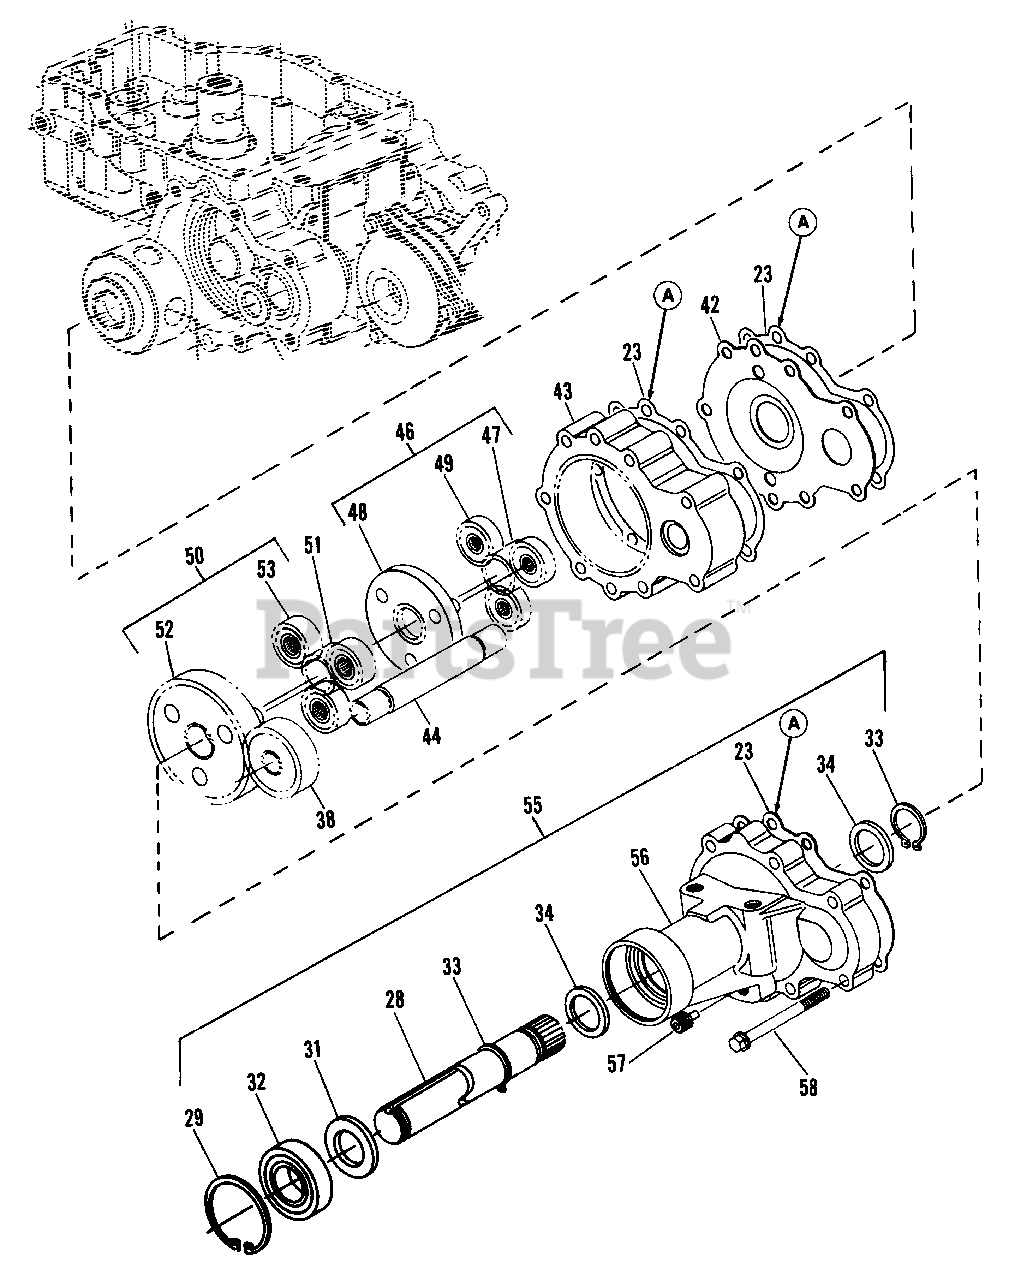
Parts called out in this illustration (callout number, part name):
23	GASKET, Axle Housing (See "A" Below)
28	SHAFT, Axle
29	RETAINING RING, Internal
31	LIP SEAL, Radial
32	BEARING, Ball
33	RING, Retainer
34	WASHER, Thrust
38	LOCK GEAR, Diff.
42	PLATE, Wear
43	RING GEAR, 54 Tooth
44	BRAKE SHAFT
46	PLANETARY GEAR (Incl. Ref. Nos. 47-49)
50	PLANETARY GEAR (Incl. Ref. Nos. 51-53)
55	AXLE HOUSING, L.H. (Incl. Ref. Nos. 28, 29, 31-34, 55 & 56)
56	HOUSING AXLE, L.H.
57	PLUG, Magnetic
58	CAPSCREW, Hex, Flange, 1/4-20 x 2-3/4
A	GASKET OVERHAUL KIT (Incl. Ref. Nos. 20, 23 & 25)
